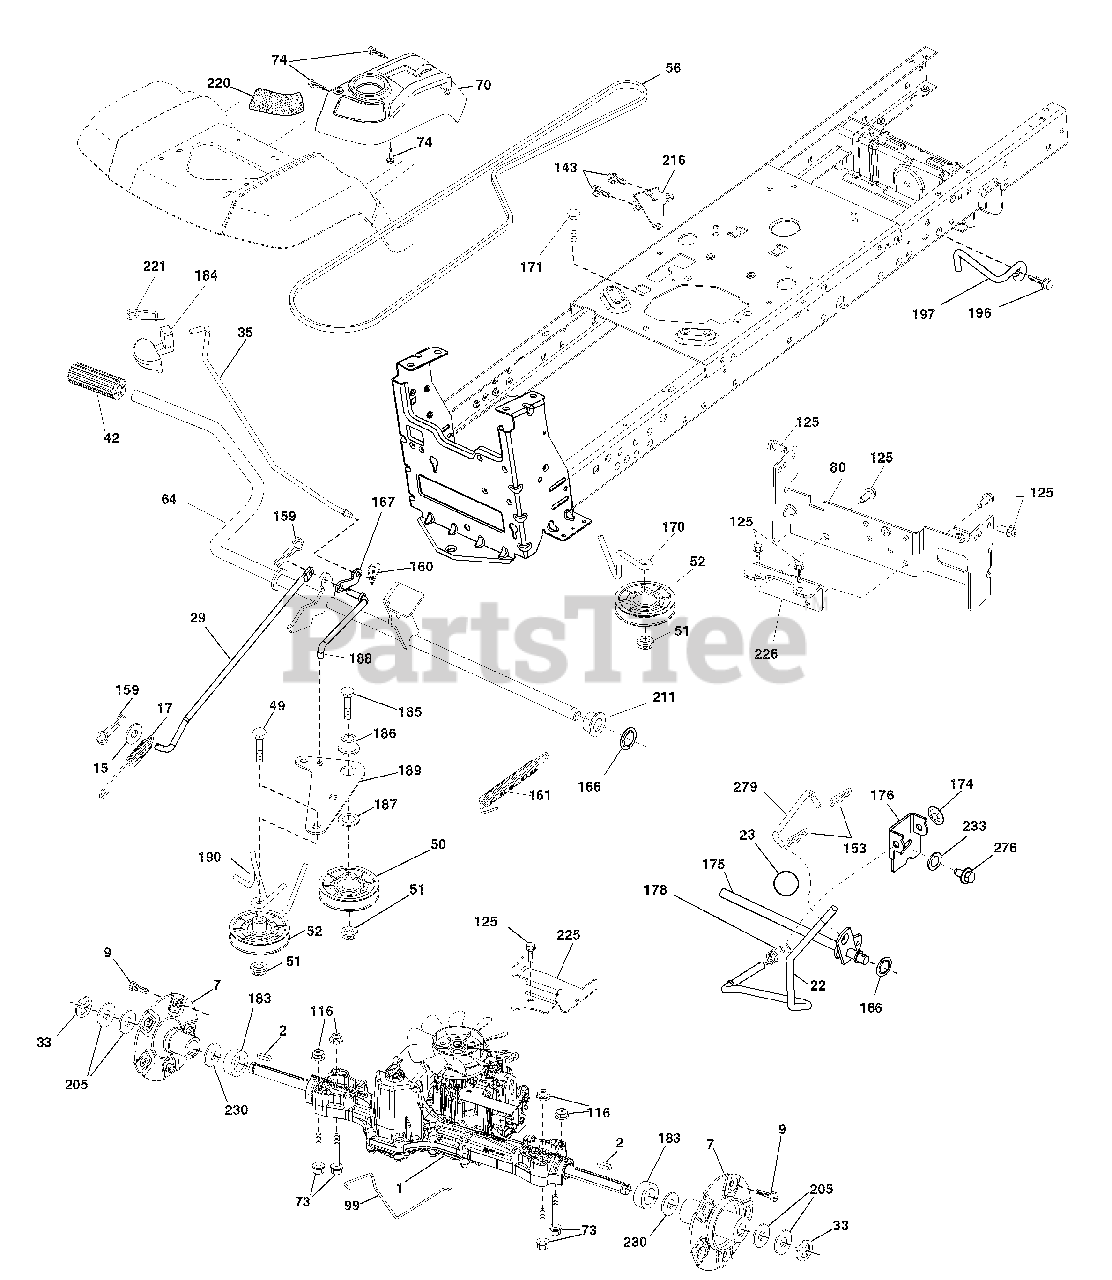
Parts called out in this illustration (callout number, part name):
1	Transaxle, TuffTorq K66
7	Hub Asm. Wheel
9	Bolt Hub Wheel
15	Washer 13/32 x 13/16 x 16 Ga.
17	Spring, Brake
23	Knob Deluxe 1/2-13 unc
29	Rod, Brake
35	Rod, Brake, Park
42	Cover, Foot Pedal
50	Pulley Idler Flat
51	Lock Nut 3/8-16
52	Idler V-Groove 910" Offset
56	V-Belt, Drive
64	Shaft Asm. Pedal Brake Control
69	Washer 11/32 x 1-5/8 x 16 Ga.
70	Control Asm.
73	Bolt Hex Flghd 5/16-18 Gr. 5
74	Screw Hx Wsh Hi-Lo 1/4 x 1/2 unc
80	Strap Torque
99	Rod Bypass
116	Nut Lock Hex Flange 5/16-18
125	Screw 5/16-18 x 3/4
143	Screw Thdrol 5/16-18 x 1/2
153	Retainer Spring
159	Pin Cotter 1/8 x 3/4
160	Retainer Clip
161	Spring, Return, Clutch
166	Nut Push .625
167	Latch Brake Parking
170	Keeper Belt Centerspan
175	Shaft Asm Shift
176	Arm Clevis Rod Shift
178	Spring Shift
183	Spacer Axle
184	Handle Parking Brake
186	Spacer Retainer
187	Washer
188	Link Clutch Ground Drive
189	Bellcrank Ground Drive
190	Keeper Bellcrank Ground Drive
195	Bracket Rod Brake
196	Screw 3/8-16 x 1
197	Bracket Clutch Anti-Rotation
205	Washer 1 1/32 x 1 5/8 x 16 Ga.
211	Bearing Nylon
216	Bracket Pulley Idler
220	Reflector RH
221	Retainer Spring Clip Handle
225	Keeper Belt Trans.
226	Bracket Mount Torque
230	Washer Hardened
233	Washer Serrated
276	Bolt Fin Hex 7/16 - 14 x 1 Gr. 5
279	Link Asm. Shift
